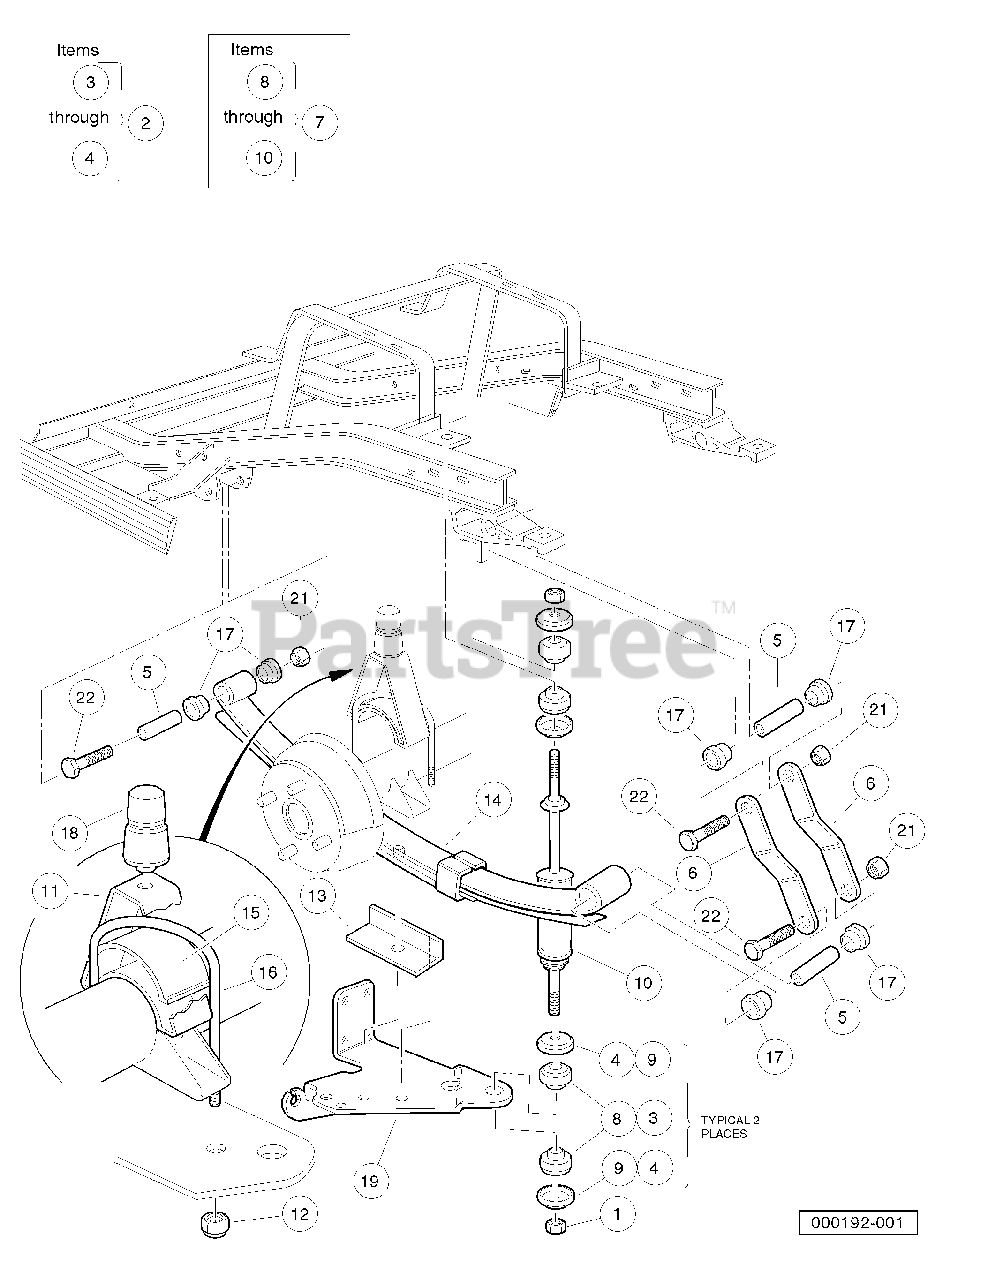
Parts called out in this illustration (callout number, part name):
1	Nut, 3/8-24 Hex
2	Kit, Shock Absorber Cushion
3	Cushion, Shock Absorber
4	Retainer, Shock Absorber Cushion
5	Bushing, Steel
6	Shackle, Rear Spring
7	Shock Absorber Kit
8	Cushion, Shock Absorber
9	Retainer, Shock Absorber Cushion
10	Shock Absorber Rear Prv Spd
11	Bumper Mount, Angled
12	Locknut, 7/16-14 Nylon Insert
13	Spring Retainer
14	Rear Leaf Spring
15	Spacer, Overload Bumper
17	Bushing, Urethane
18	Bumper, Jounce
19	Bracket, Left-Hand
20	Bracket, Right
21	Locknut, 3/8-16 Hex
22	Screw, 3/8-16 X 3.375 Hex Cap
